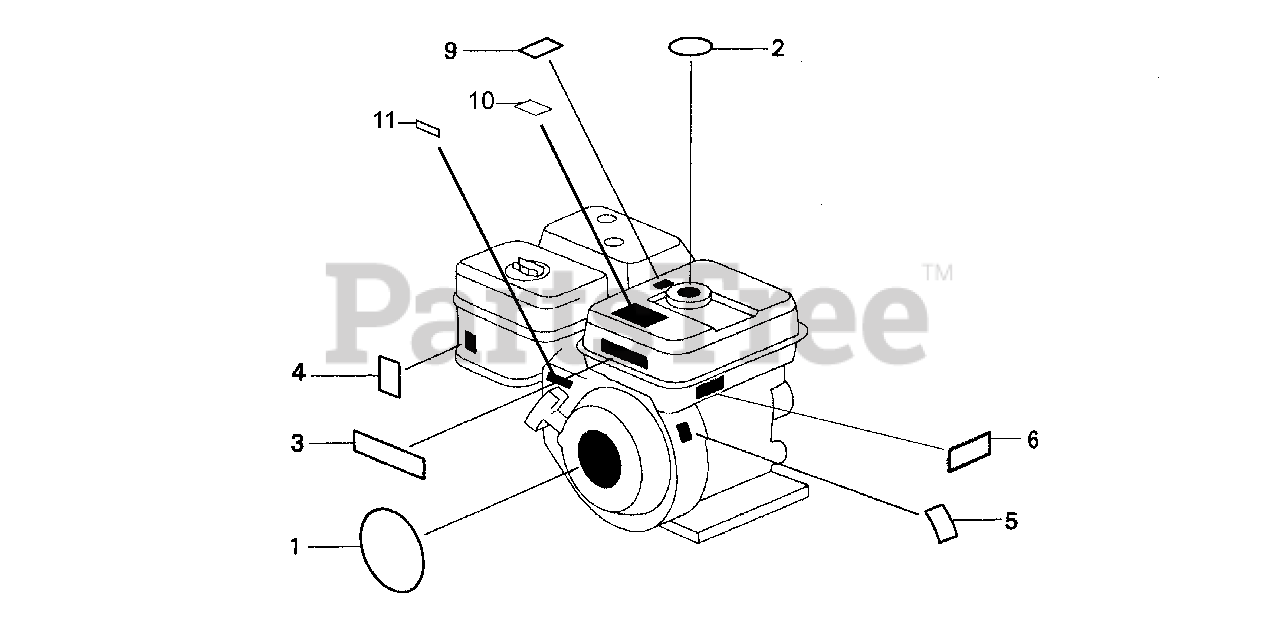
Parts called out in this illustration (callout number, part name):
1	EMBLEM (4.0)
2	MARK, CAUTION
3	LABEL, CAUTION (ENGLISH, ETC.)
4	MARK, CHOKE
5	LABEL, SPECIFICATION (EXTERNAL)
6	MARK, OIL ALERT (ENGLISH)
9	LABEL, FUEL CAUTION
